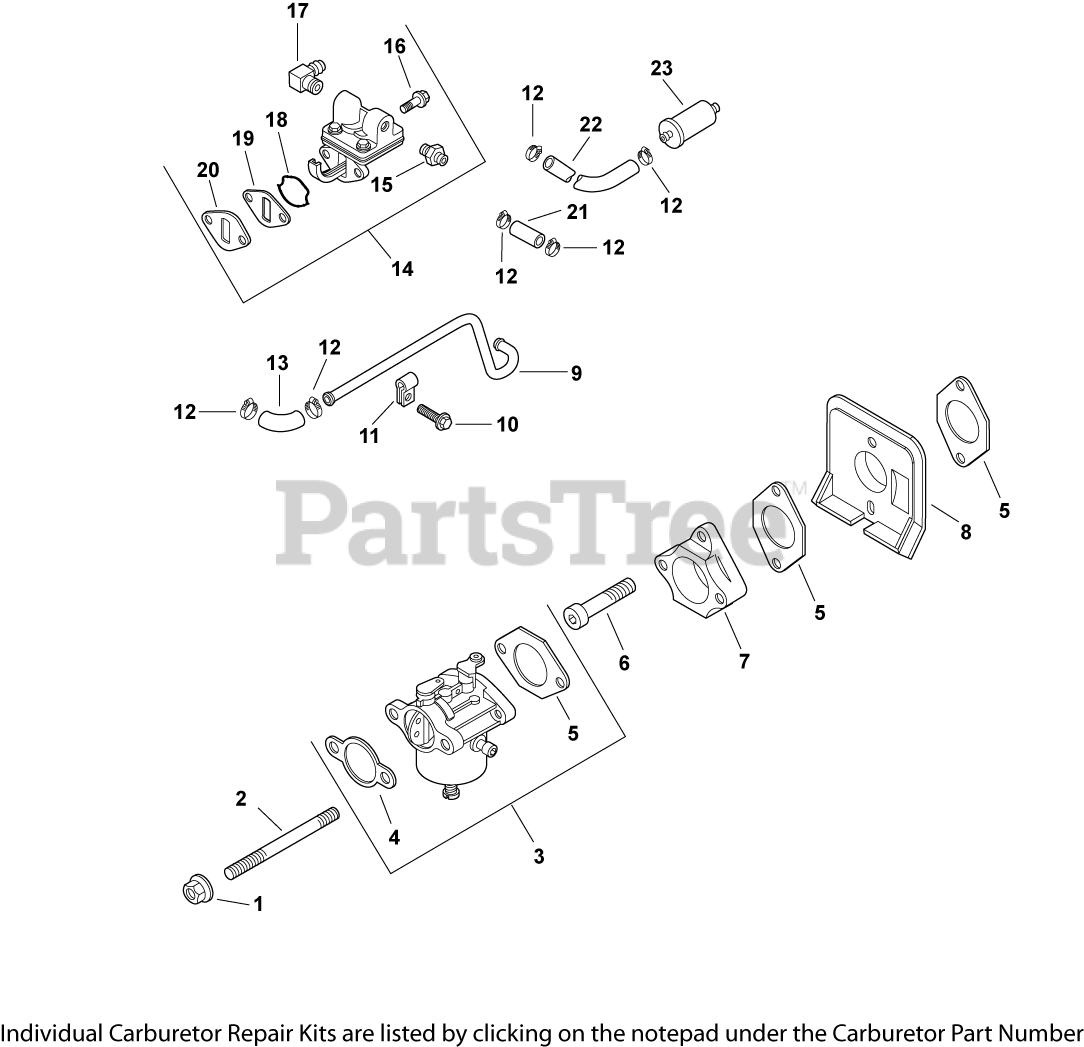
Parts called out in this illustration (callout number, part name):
1	NUT, FLG M6X1.0
2	STUD,M6X1.0X116
3	KIT, CARBURETOR w/GASKETS
4	GASKET, AIR CLEANER BASE
5	GASKET, CARBURETOR
6	SCREW, SKT CAP M6X1.0X35
7	ADAPTER, CARBURETOR
8	DEFLECTOR, HEAT
9	LINE, FUEL - DISCONTINUED
10	SCREW, FLG THD FRM M5X.8X10
12	CLAMP, HOSE (KM)-USE 25 237 31-S
13	HOSE, FUEL LOW-PERMEATION
14	KIT, FUEL PUMP
15	KIT, STRAIGHT FITTING
16	SCREW, LBD SKT M6x1.0x20-(#25086403S)
17	CONNECTOR, 90 DEG. HOSE
18	O-RING, FUEL PUMP
19	SPACER, FUEL PUMP
20	GASKET, FUEL PUMP
21	LINE - DISCONTINUED
22	LINE, FUEL 2" PUMP-FILTER
23	FILTR,FUEL 75 MICRON (GRAVTY FEED)
